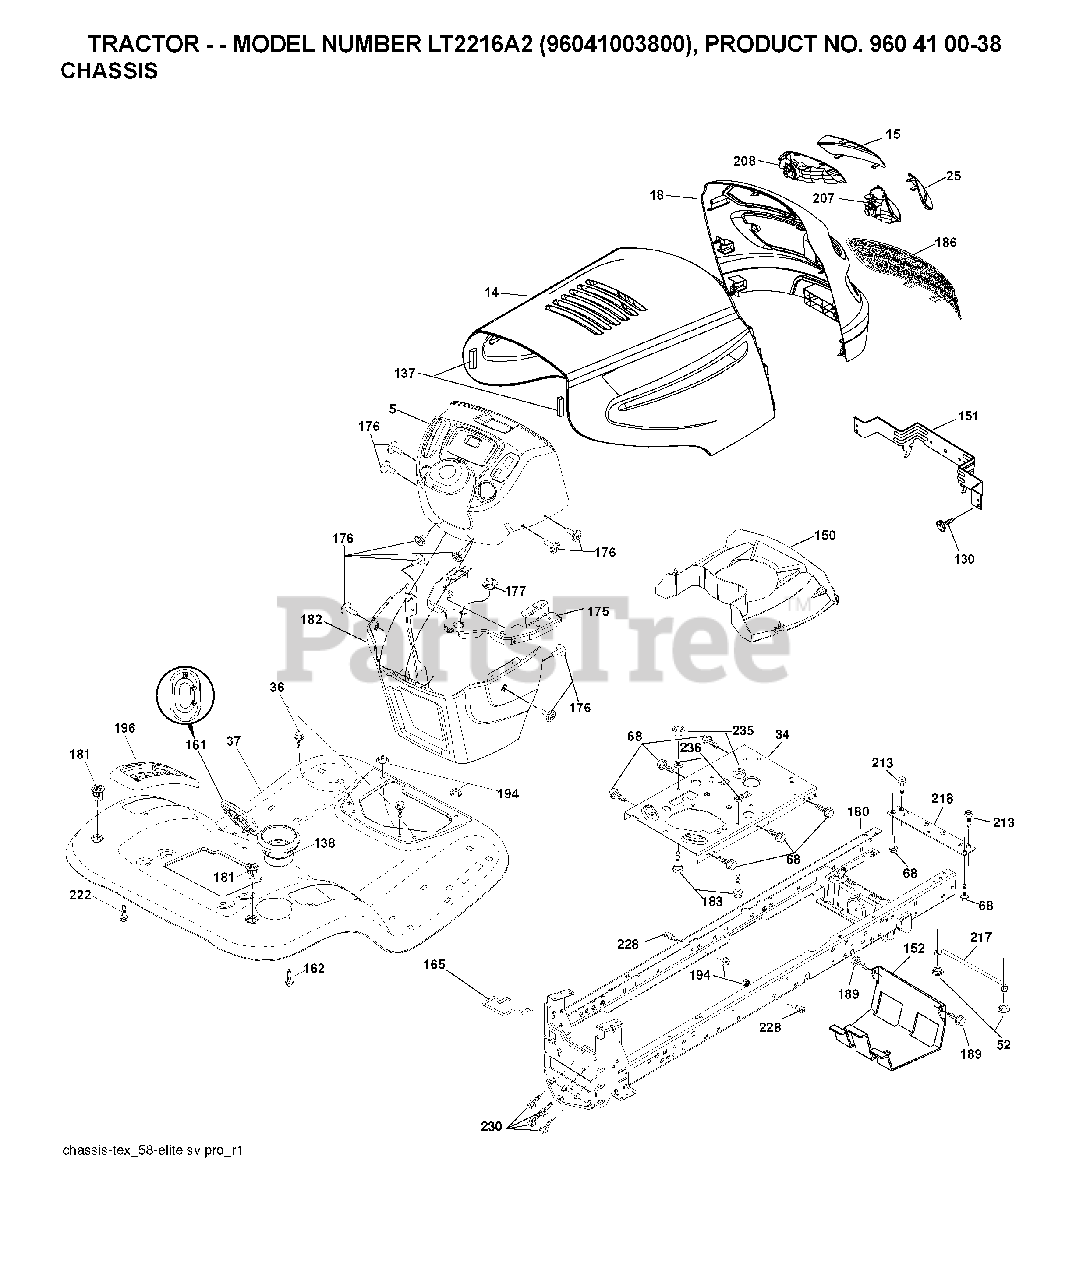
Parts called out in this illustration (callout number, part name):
34	PLATE.ENGINE.WELDED.CHASSIS
36	SCREW 3/8-16X3/4
52	LOCKNUT
130	SCREW
137	BUMPER.HOOD.LARGE.1.75"
138	CUPHOLDER.TL.TEX.BLACK
151	BRACKET PIVOT
152	SHIELD BROWNING
161	WINDOW.FUEL.LT.TEX.BLACK
162	SCREW.HI-LO.CONSOLE
165	SUPPORT.TANK.REAR.W/TE
175	CROSSMEMBER.LT
176	SCREW.#10-24X5/8.RN.QU
177	BUSHING STEERING
180	CHASSIS
181	FEND/FTRST.PCH.CPH.NFW
182	DASH.LOWER.LT.CCS
183	BOLT.5/16-18X1-1/4 FULL.THREAD
189	SCREW
194	NUT LOCK HEX FLANGE 5/16-18
196	CONSOLE.ASM.DECK.LIFT.TLT.BLAC
207	BEZEL GRILL RH
208	BEZEL GRILL LH
213	BOLT
217	ROD PIVOT CHASSIS/HOOD
218	X-PIECE.HOOD.STOP.NON/
222	SCREW.1/4-20X5/8
228	STUD.FASTNER.W/ANTI-ROTATE
230	SHOULDER BOLT 5/16-18TT
235	SPACER FENDER
236	NUT.CENTERLOCK.5/16-
